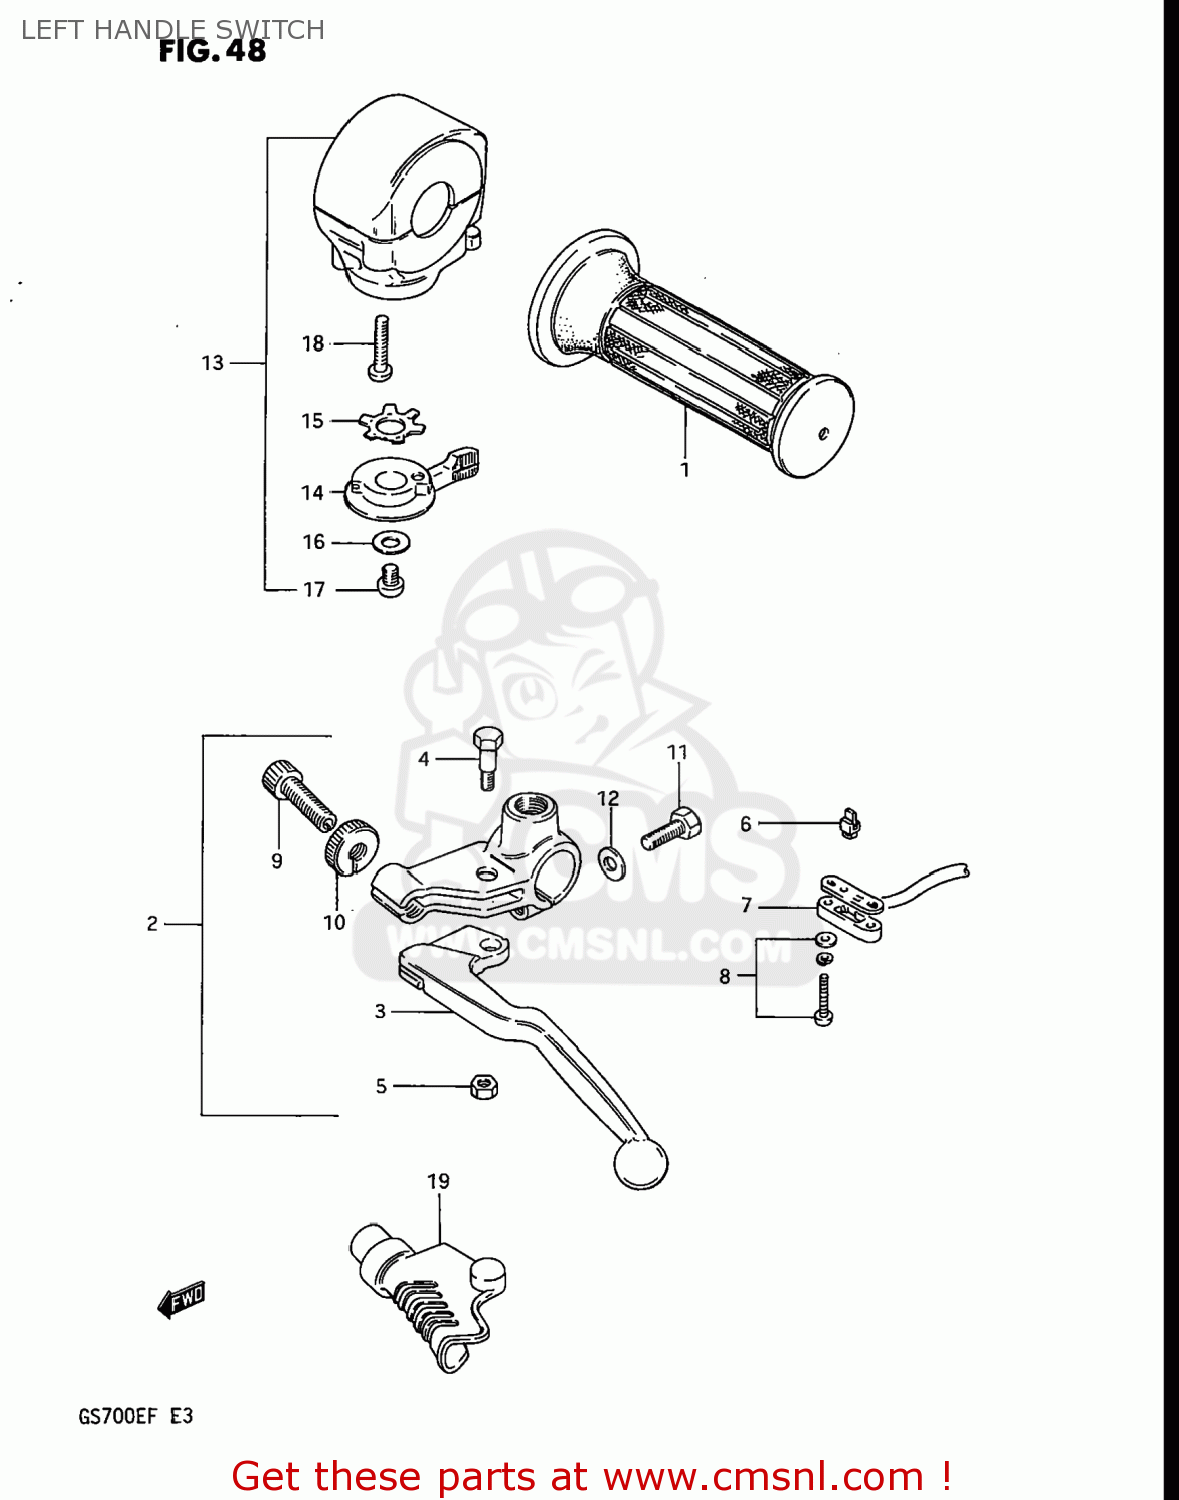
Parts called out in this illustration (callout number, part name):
1	GRIP,L
2	LEVER ASSY,CLUTCH
3	LEVER,CLUTCH
4	BOLT,LEVER PIVOT
5	NUT 6MM
6	CONTACT,SWITCH
7	COVER,FR BK TERMINAL BASE
8	SCREW
9	ADJUSTER,CABLE
10	NUT,CABLE ADJUSTER LOCK
11	BOLT
12	WASHER
13	SWITCH ASSEMBLY,HANDLE,LEFT
14	LEVER,STARTER
15	WASHER
16	WASHER 6MM
17	SCREW
18	SCREW
19	COVER,CLUTCH LEVER
